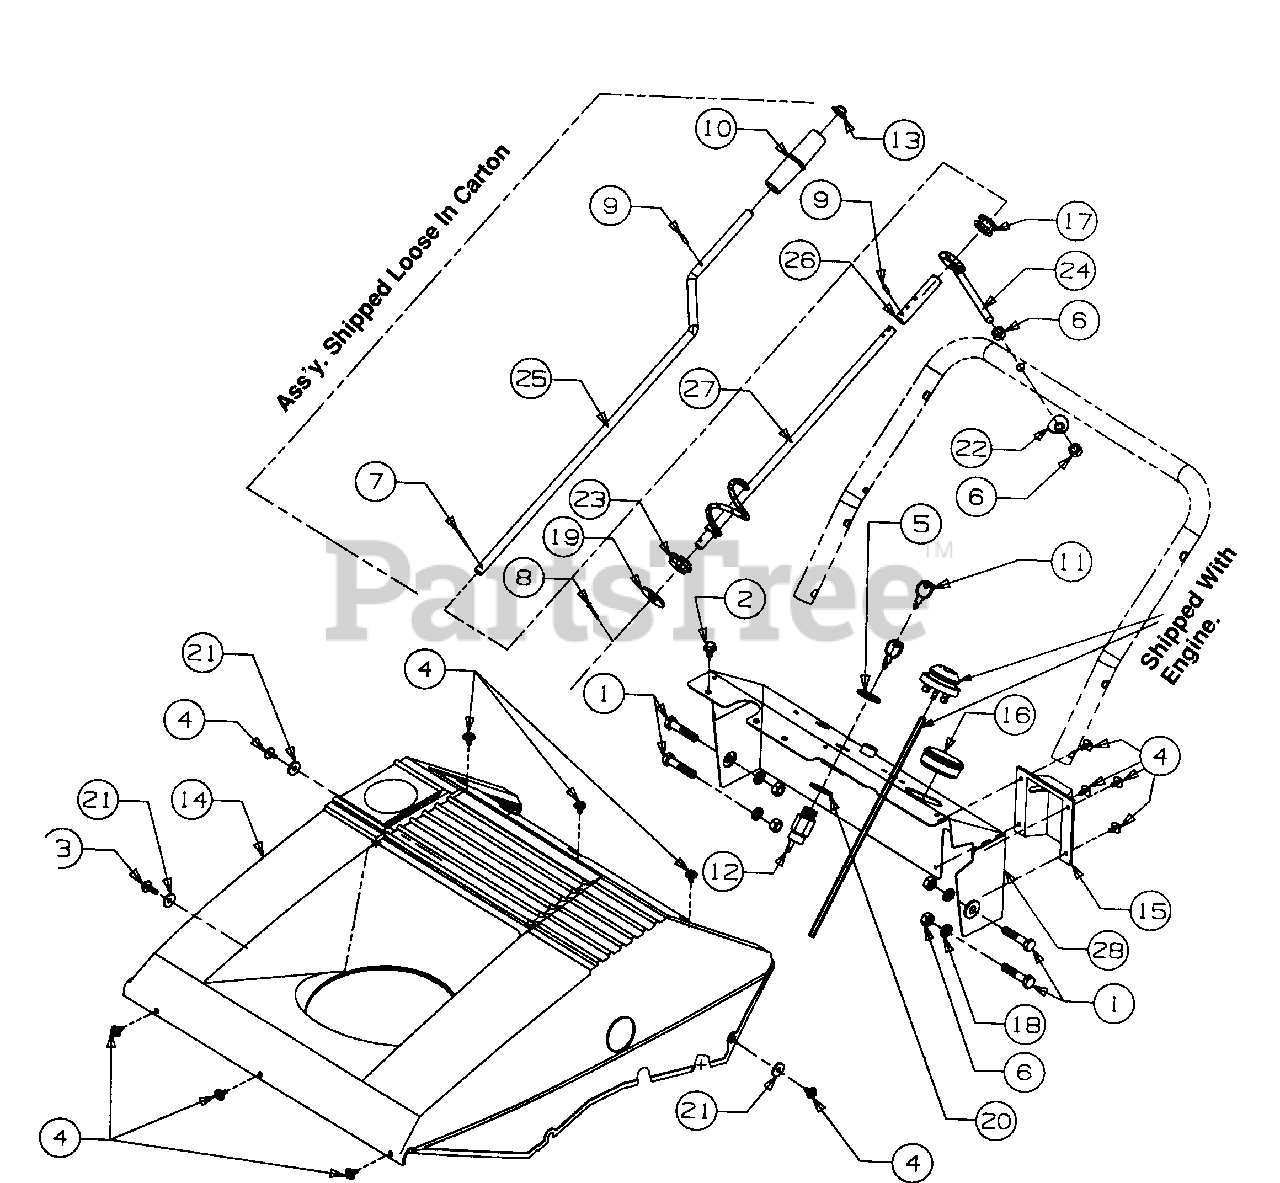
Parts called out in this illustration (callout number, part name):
1	Screw - Hex
2	Screw - Hex Washer
3	Screw - Hex
4	Screw - Hex
5	Nut - Jam
6	Nut - Hex
7	Pin - Cotter
8	Pin - Cotter
9	Pin Roll
11	Key - Ignition
12	Switch
13	Cap - Push
14	Shroud - Black
15	Cover - Choke
16	Plug - Insert
17	Grommet - Rubber
18	Washer - Lock
19	Washer - Flat
20	Washer - Lock-Internal
21	Washer - Flat
22	Washer - Saddle
23	Bushing - Hex
24	Eyebolt - Chute Crank
26	Spacer
27	Crank - Chute 13.5" Lg.
